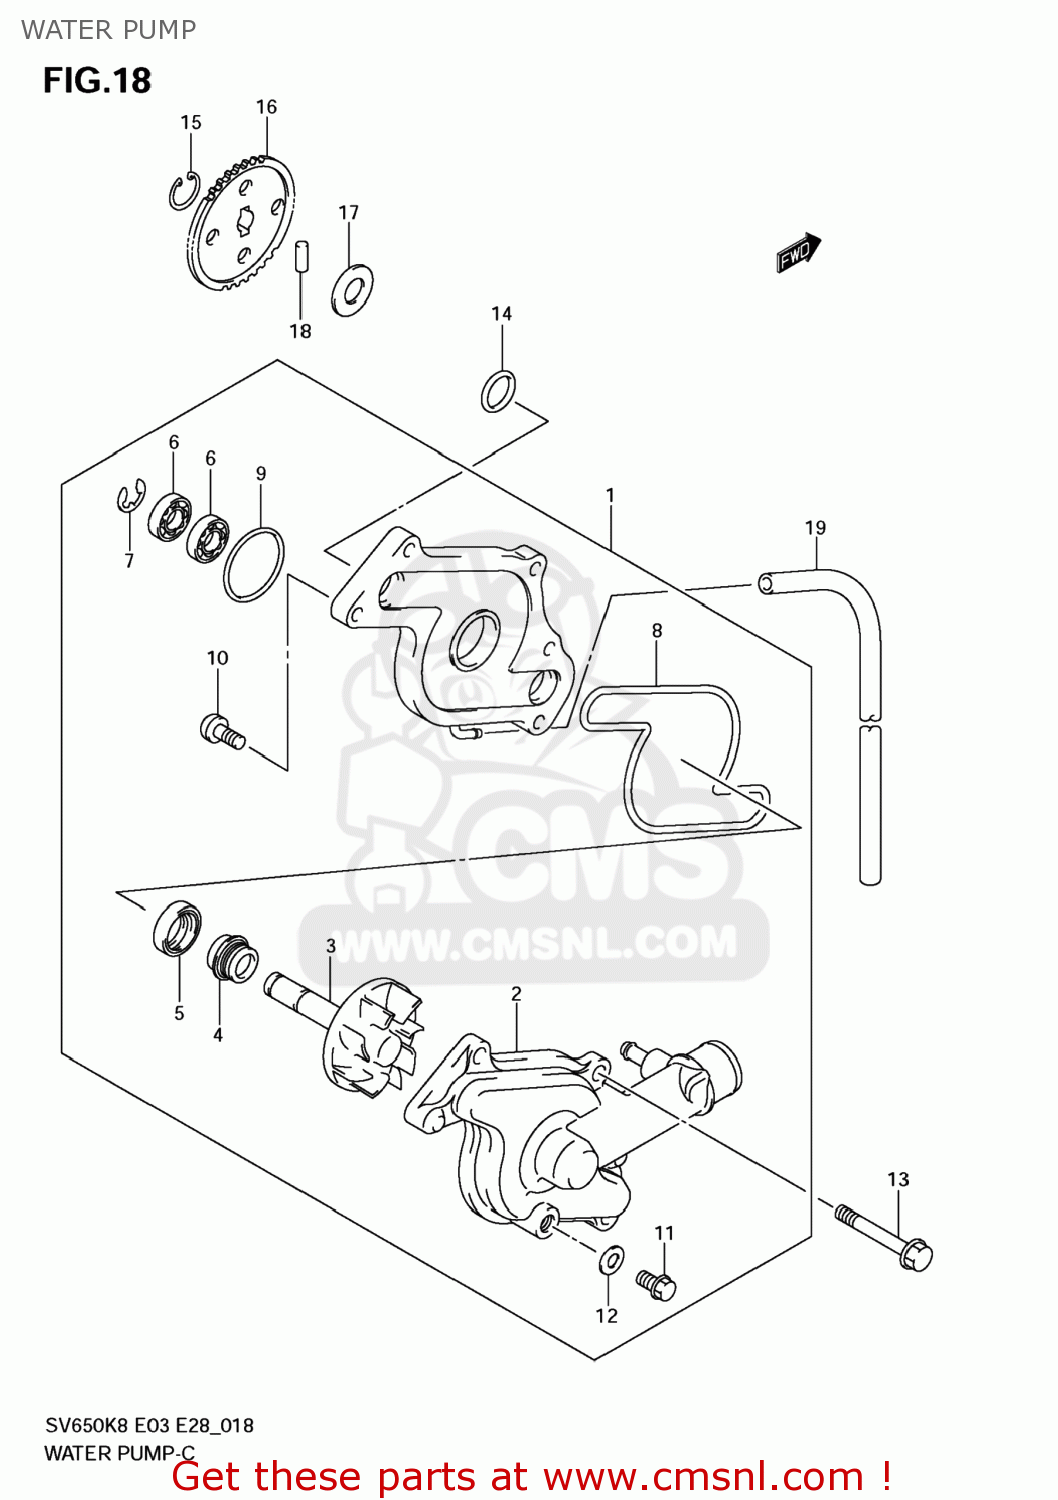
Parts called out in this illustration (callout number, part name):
1	PUMP ASSY,WATER
2	CASE,WATER PUMP
3	IMPELLER/SHAFT
4	SEAL,MECHANICAL
5	SEAL,OIL(10X21X5)
6	BEARING
7	E RING
8	O RING
9	O RING,WATER PUMP HOLDER
10	SCREW 6X16
11	BOLT,DRAIN
12	GASKET(8.2X14X1) (NAS)
13	BOLT(6X55)
14	O RING(D:2.4,ID:21.8)
15	CIRCLIP,10MM
16	GEAR,WATER PUMP DRIVEN
17	SHIM(10X18X0.5)
18	ROLLER(4X13.8)
19	HOSE(3.5X6.5X600)
